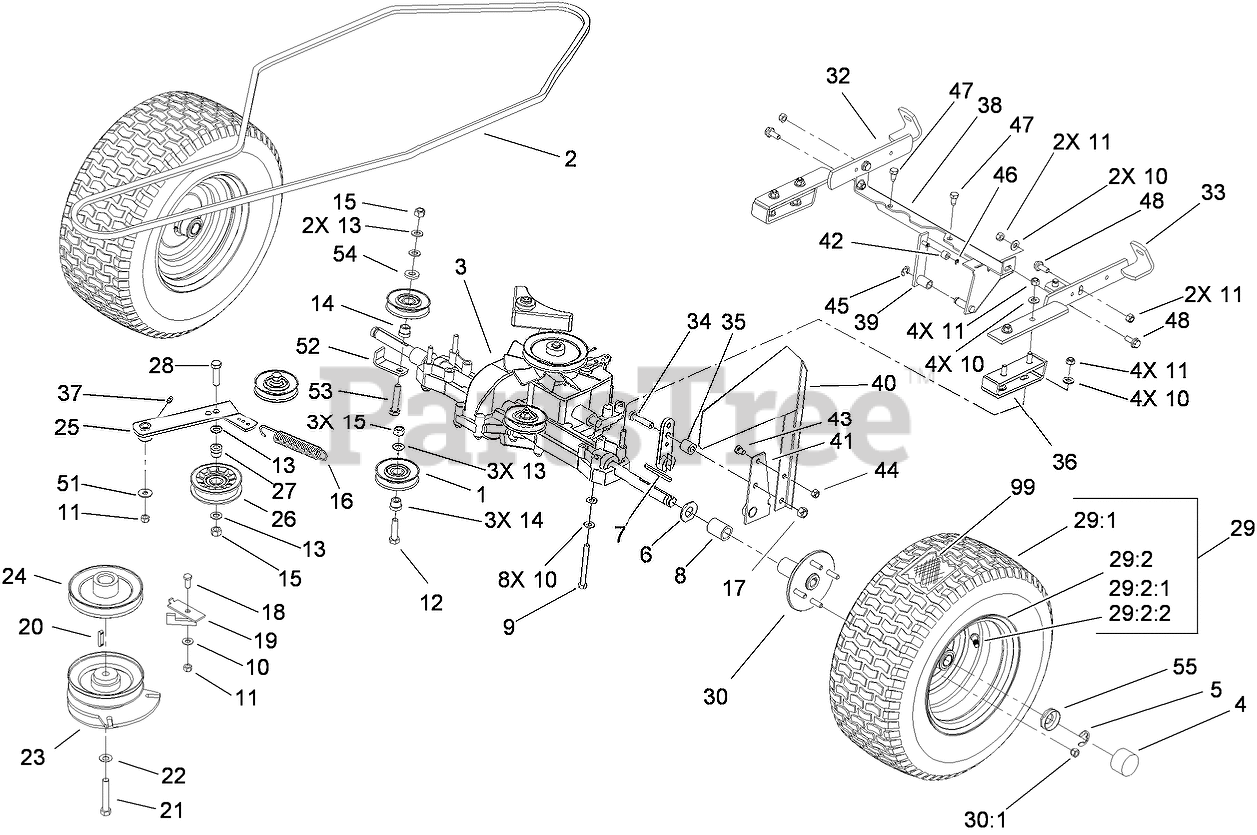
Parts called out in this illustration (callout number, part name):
1	PULLEY-IDLER
2	V-BELT-TRACTION
3	TRANSMISSION
4	CAP-HUB
5	CLIP-SPRING
6	WASHER
7	KEY-SQUARE
8	SPACER-AXLE
9	SCREW-HH
10	WASHER-PLAIN
11	NUT-LOCK, NI
12	SCREW-HH
13	WASHER-FLAT
14	BUSHING-IDLER
15	NUT-LOCK, NI
16	SPRING
17	NUT-LOCK, NI
18	SCREW-HH
19	RETAINER
20	KEY-SQUARE
21	SCREW-HH
22	WASHER-SPRING, BELLEVILLE
23	CLUTCH-ELECTRIC
24	PULLEY-ENGINE
25	ARM-IDLER
26	PULLEY-IDLER
27	BUSHING-IDLER
28	SCREW-HH
29	TIRE AND WHEEL ASM
29:2	WHEEL ASM
29:2:1	RIM
29:2:2	Valve-Tire
30	HUB-WHEEL
30:1	NUT-LUG
32	Bracket-Right
33	Bracket-Left
34	SCREW-HH
35	SLEEVE
36	Plate-Reinforcing
37	FITTING-GREASE
38	Bar ASM
39	Arm-Switch
40	ARM-CONTROL, CRUISE
42	Roller
43	SCREW-HH
44	NUT-LOCK, NI
45	Stirrup
46	STIRRUP
47	SCREW-THREAD FORMING
48	SCREW-HEX
51	WASHER-PLAIN
52	RETAINER-BELT
53	SCREW-HH
54	WASHER-FLAT
55	RETAINER-CAP, HUB
